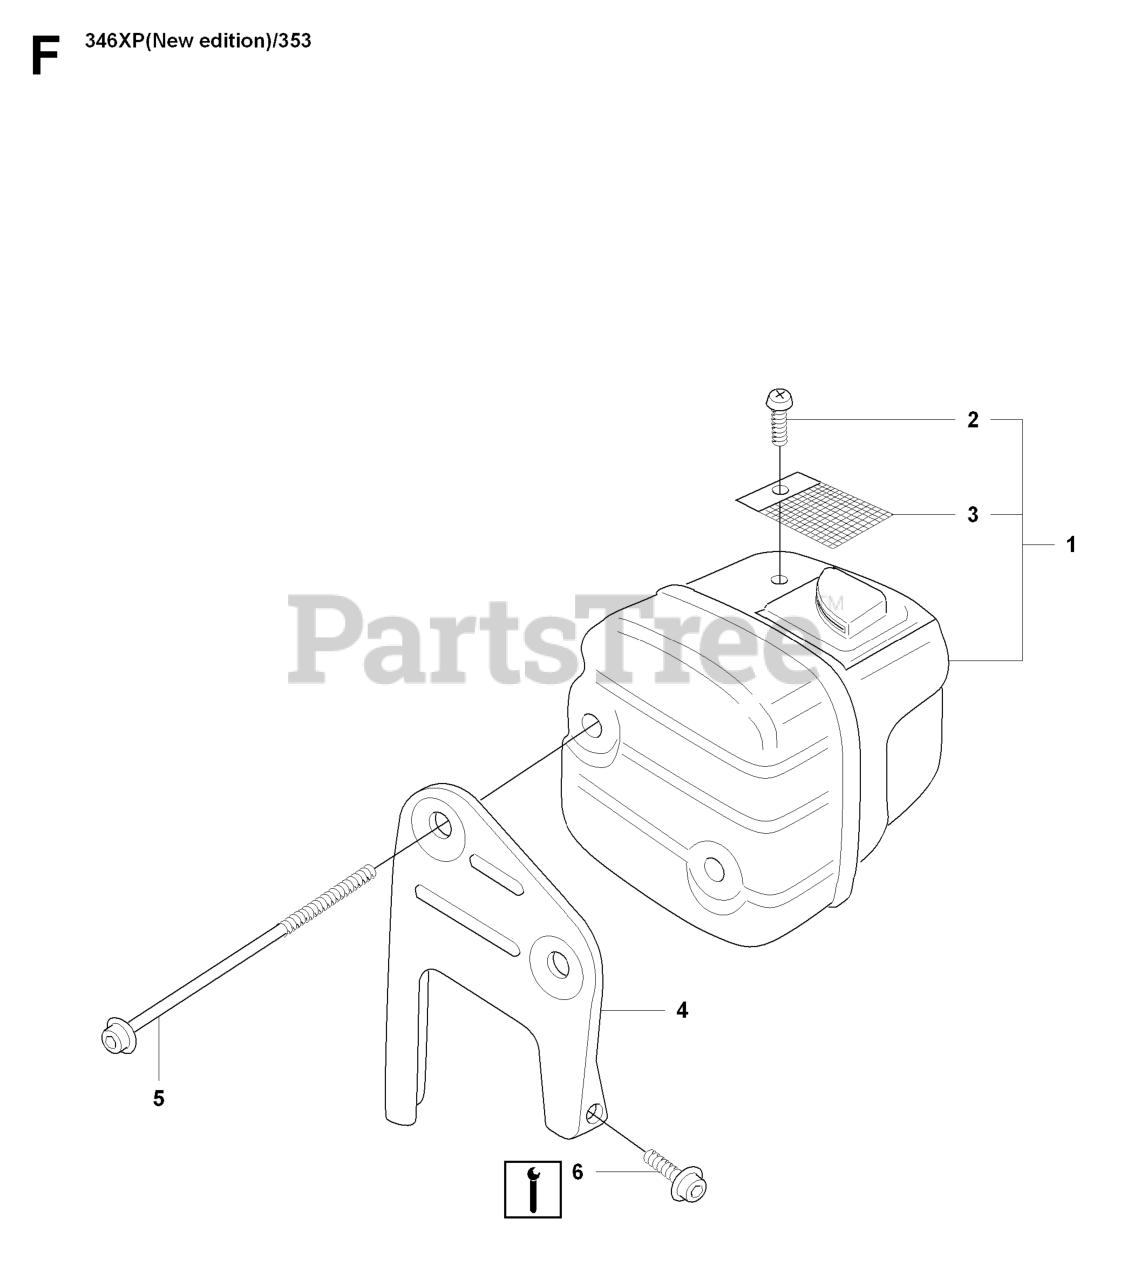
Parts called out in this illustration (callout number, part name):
1	MUFFLER ASSY
1	MUFFLER
3	RP SCREEN
